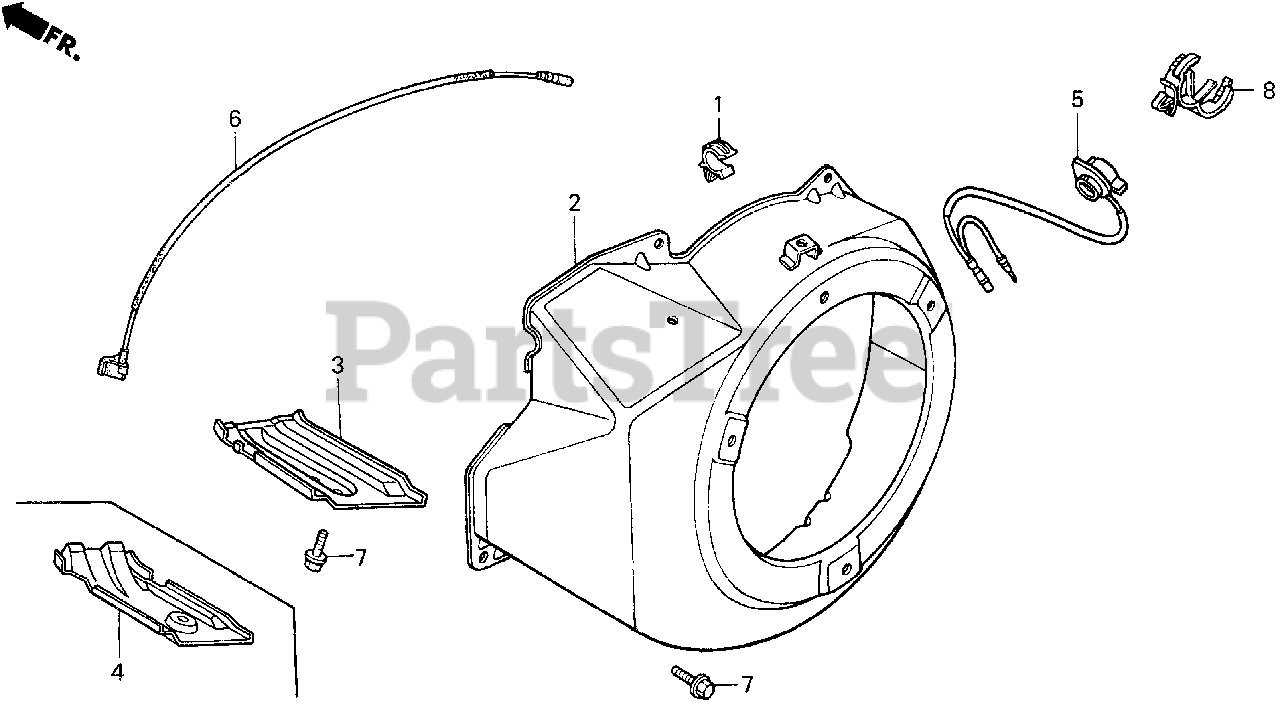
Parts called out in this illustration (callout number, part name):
1	CLIP, TUBE
2	COVER, FAN *NH1* (BLACK)
5	SWITCH ASSY., ENGINE STOP
6	WIRE, STOP SWITCH (430MM)
7	BOLT, FLANGE (6X12) (CT200)
8	CLIP, WIRE HARNESS
